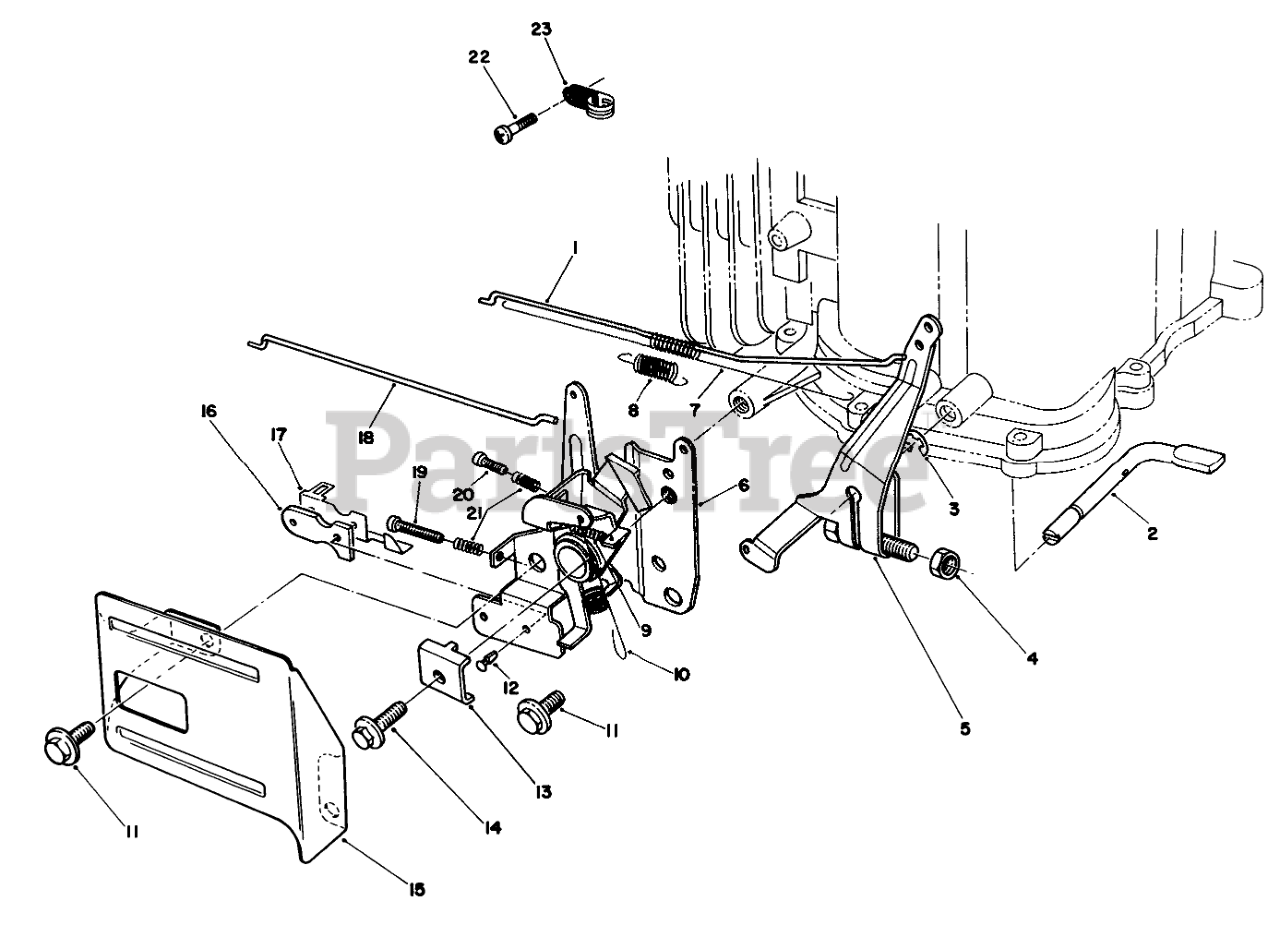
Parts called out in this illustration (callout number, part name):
1	Rod-Carburetor
2	SHAFT
3	E-RING
4	Nut
5	ARM ASM
6	THROTTLE
7	SPRING
8	SPRING
9	SPRING
10	SPRING
12	RIVET
13	CLAMP-CABLE
15	THROTTLE GUARD
16	INSULATOR-KILL SWITCH
17	TERMINAL-KILL SWITCH
18	Rod-Choke
19	SCREW
20	SCREW
21	SPRING
22	SCREW
23	Clamp
